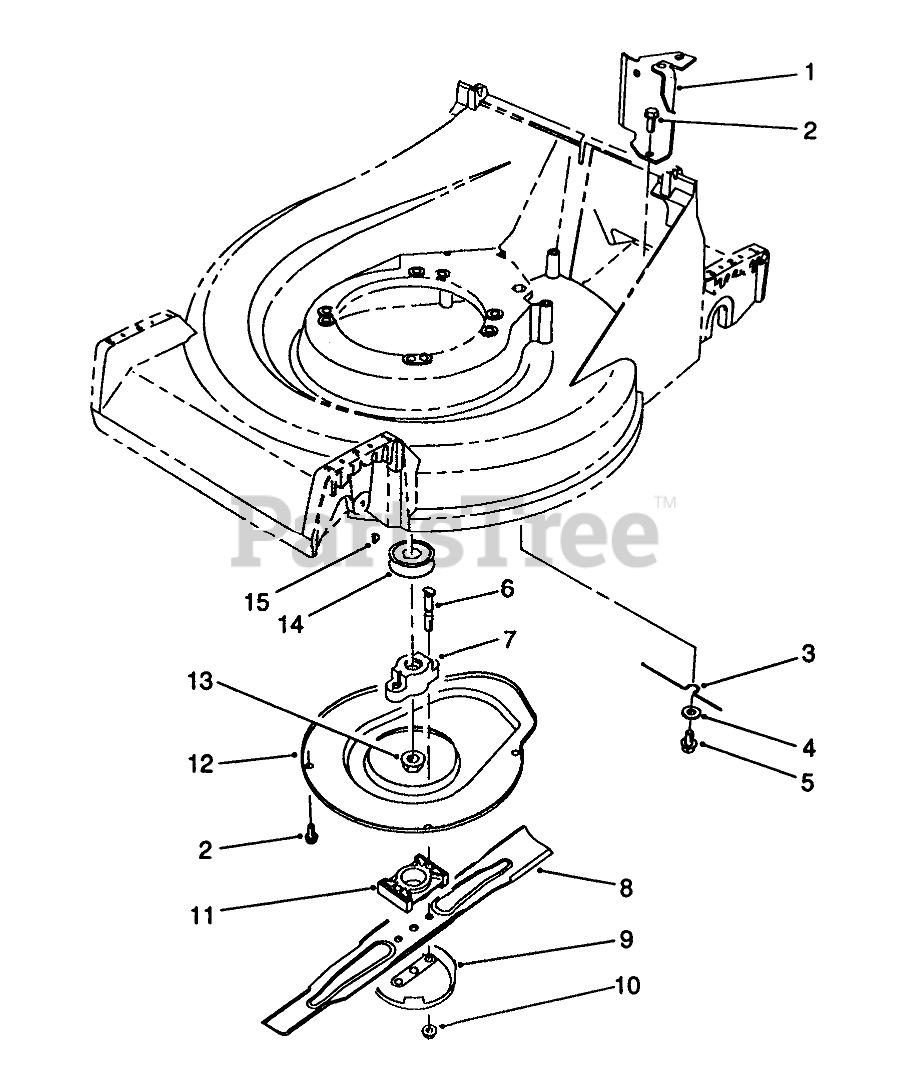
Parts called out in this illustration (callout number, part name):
1	Bracket-Cable Support
2	SCREW-HWHTF
3	RETAINER-BELT
4	WASHER-FLAT
5	SCREW-HHFTF
6	BOLT-BLADE
8	Key
9	Anti Scalp Cup
10	NUT-LOCK
11	SPACER-BLADE
12	Cover
13	NUT-LOCK, NI
14	PULLEY
15	KEY-WOODRUFF
